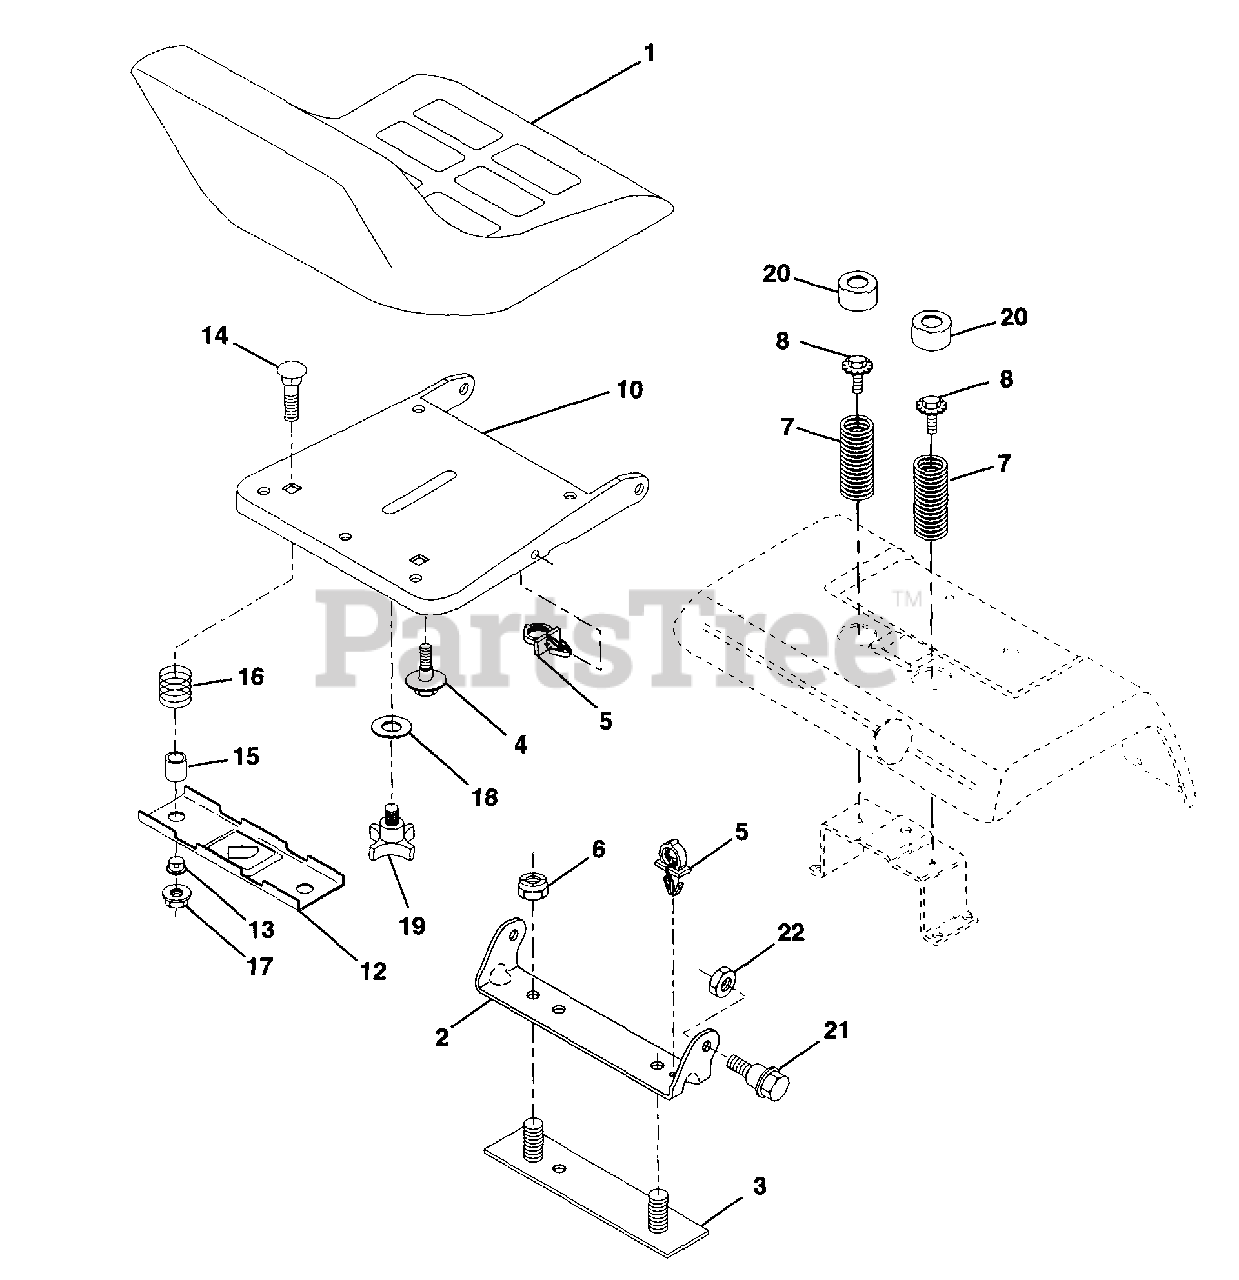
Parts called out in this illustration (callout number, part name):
1	Seat
2	Bracket, Pivot Seat
3	Strap, Fender
4	Bolt, Shoulder 5/16-18 X .62
5	Clip, Push In Hinged
6	Nut, Lock Hex W/Ins. 3/8-16 Unc
7	Spring, Seat Cprsn
8	Bolt 5/16-18unc x 3/4 W/Sems
10	Pan, Seat
12	Bracket, Mounting Switch
13	Bushing, Snap
14	Bolt, Carriage 1/4-20 X 1-3/8
15	Spacer, Split
16	Spring, Cprsn
17	Nut, Lock 1/4 Lge Flg Gr. 5
18	Washer 17/32 X 1-3/16 X 12 Ga.
19	Knob, Seat 1/2-13 Unc
20	Cap, Spring Seat
21	Bolt, Shoulder 5/16-18 Unc-2A
22	Nut, Crownlock 5/16-18 Unc
